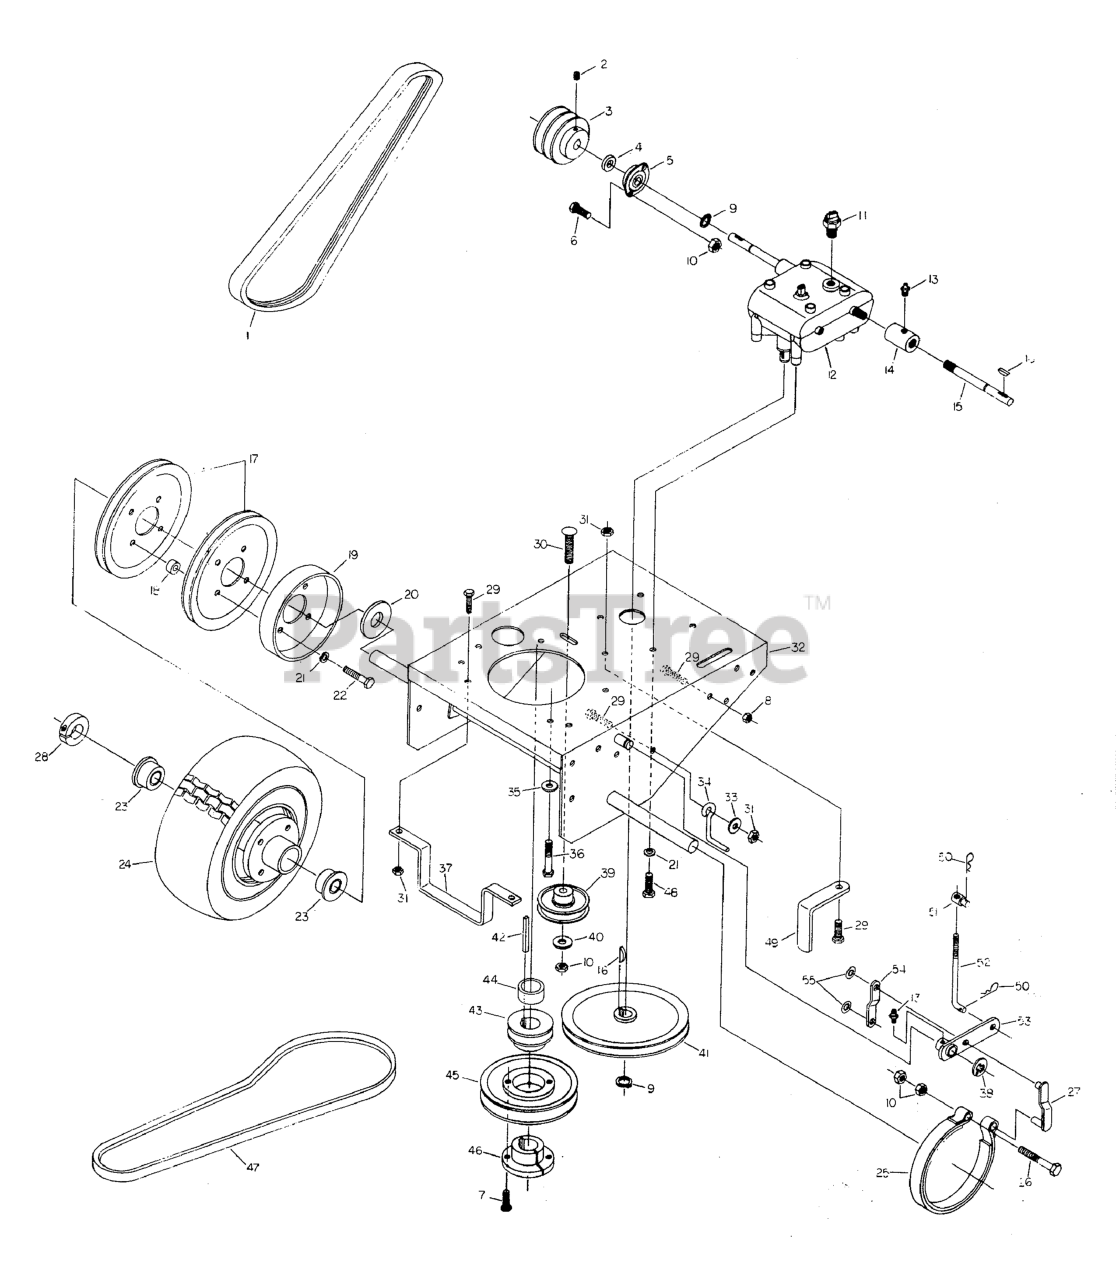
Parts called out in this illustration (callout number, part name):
1	BELT, Double-A Section
2	SET SCREW, 5/16-18 X 3/8"
3	PULLEY, Double-A Section
4	Transmission Shaft Spacer
5	Bearing With Flange
6	BOLT, 3/8-16 X 1" GD5 CZ
7	BOLT, 1/4-20 x 3/4
8	NUT, 5/16-18 HEX SERRATED FLANGE (LARGE)
9	RING, External, Snap
10	NUT, 3/8-16 HEX NYLON LOCK
11	Transmission Switch
12	Model 700-032 5 Speed Gear Box
13	GREASE FITTING
14	Coupler With Zerk
15	Shaft Extension
16	KEY, #9 Woodruff
17	PULLEY, Ground Drive
18	SPACER, Pulley
19	BRAKE DRUM
20	WASHER, 1" SAE
21	WASHER, 5/16 LOCK CZ
22	BOLT, 5/16-18 x 1-1/2
23	Wheel Bearing
24	Wheel/Tire Assembly
25	Brake Bank
26	BOLT, 3/8-16 X 2, GD5, CZ
27	Brake Connector Assembly
28	COLLAR, 1" Split
29	BOLT, 5/16-18 X 1 GD5 YZ
30	3/8-16 x 2 Carriage Bolt
31	NUT, 5/16-18 Hex Nylon Lock
32	Rear Deck Assembly
33	WASHER, 5/16" SAE
34	Round Belt Guide
35	Disc Spring
36	BOLT, M8-1.25 X 25MM GR 8.8
37	Belt Guide
38	5/8 E Ring
39	IDLER PULLEY ASSEMBLY
40	WASHER, 3/8 SAE
41	Transmission Pulley
42	KEY, 1/4 SQ. X 2-1/2
43	Pulley (To Transmission)
44	SPACER, 1.13 X 1.50 X .50
45	PULLEY, Spindle
46	BUSHING, Tapered Hub
47	Transmission Belt
48	BOLT, 5/16-18 X 3/4 GD5
49	Flat Belt Guide
50	HAIRPIN CLIP
51	Rod Swivel
52	Brake Rod
53	Brake Arm Assembly Right
53	Brake Arm Assembly Left
54	Brake Connector
55	3/8 Push Nut
